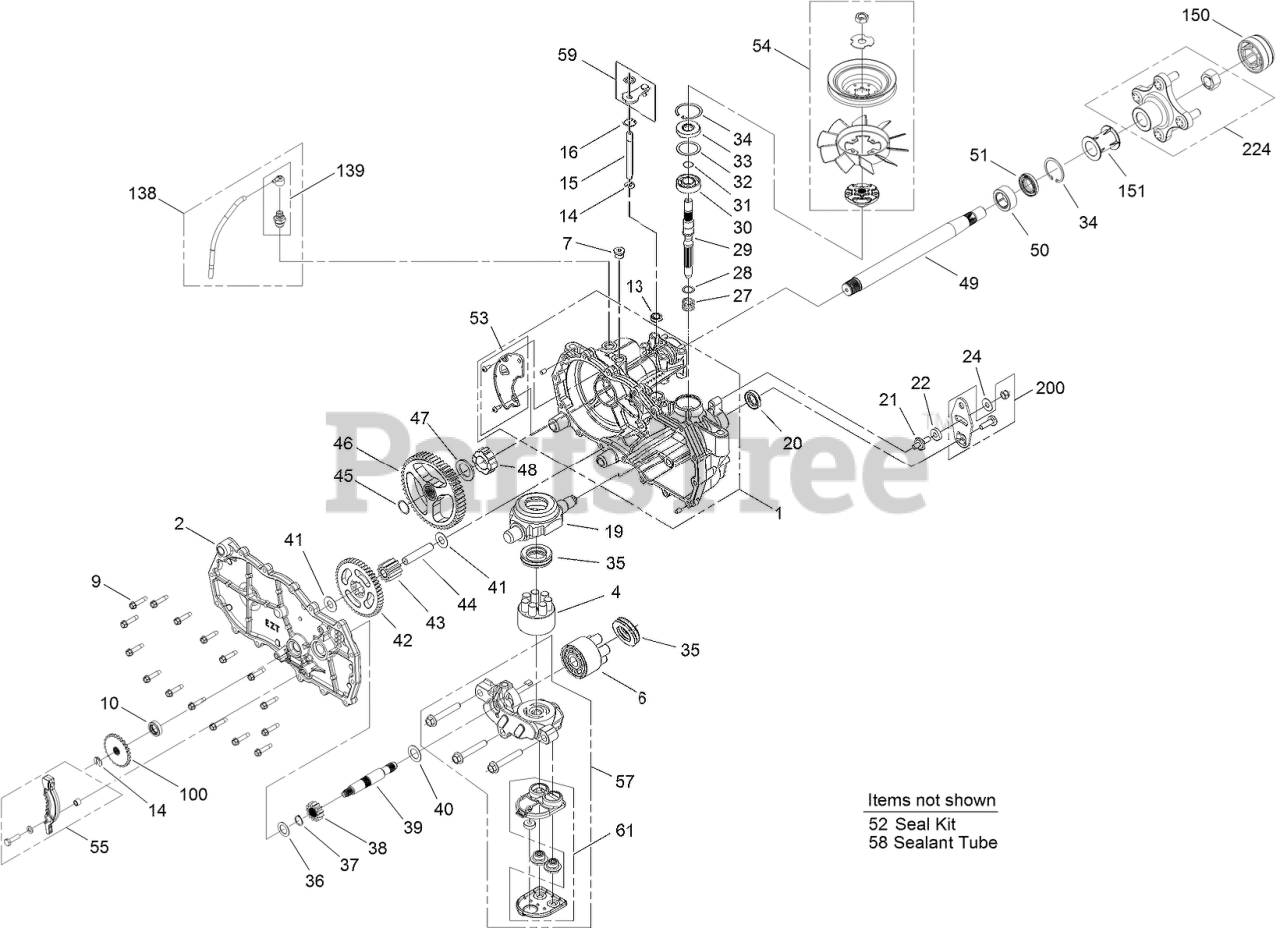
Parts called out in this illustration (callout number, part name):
1	MAIN HOUSING ASM
2	SIDE ASM
4	PUMP BLOCK ASM
6	CYLINDER BLOCK KIT
7	PLUG-THREAD, STRAIGHT
9	SCREW-HHF
10	SEAL-OIL
13	SEAL-LIP
14	RING-RETAINING, EXTERNAL
15	ROD-BYPASS
16	RING-RETAINING, INTERNAL
19	SWASHPLATE-TRUNNION
20	SEAL-LIP
22	PUCK-FRICTION
24	WASHER
27	SPRING-COMPRESSION
28	WASHER
29	SHAFT-INPUT
30	BEARING-BALL
31	RING-RETAINING
32	SPACER
33	SEAL-LIP
34	RING-RETAINING
35	BEARING-THRUST
36	WASHER-FLAT
37	RING-RETAINING
38	GEAR-PINNION, 13T
39	SHAFT-MOTOR
40	WASHER
41	WASHER
42	GEAR-10T/48T
43	GEAR-JACKSHAFT, 10T
44	PIN-JACKSHAFT
45	RING-SPIRAL, RETAINING
46	GEAR-52T, BULL
47	WASHER
48	BEARING-SLEEVE
49	SHAFT-AXLE
50	BUSHING-AXLE
51	SEAL-LIP
53	EXPANSION PLATE KIT
54	FAN PULLEY KIT
55	BRAKE ARM KIT
57	CENTER SECTION FILTER KIT
59	BYPASS ARM KIT
61	FILTER KIT
100	DISC-BRAKE, COG
138	BREATHER KIT
139	BREATHER ASM
150	COVER-NUT, AXLE
151	TUBE-AXLE
200	CONTROL ARM KIT
224	HUB ASM
